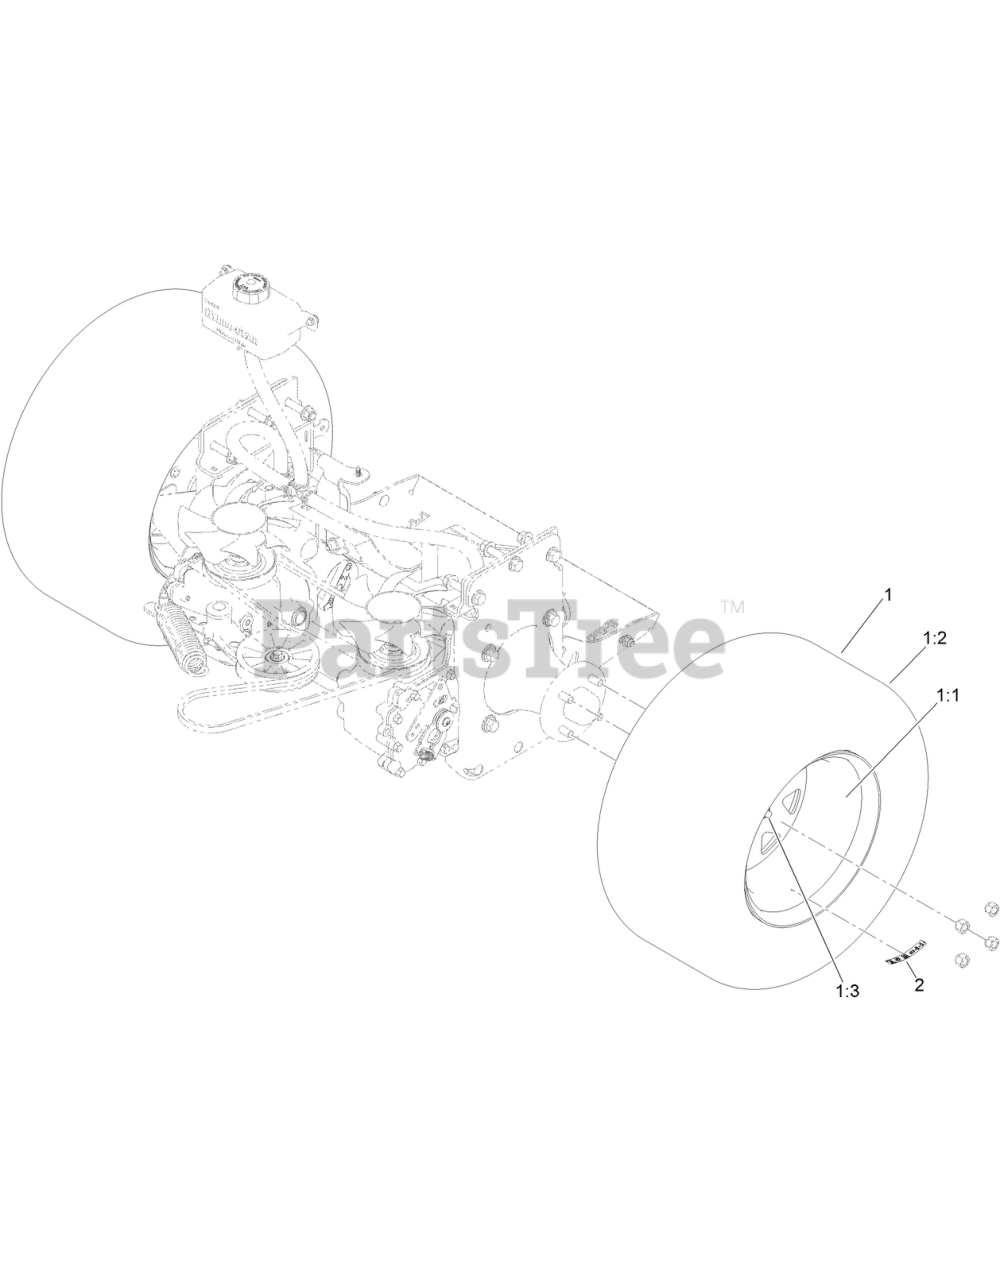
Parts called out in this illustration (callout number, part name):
1	WHEEL AND TIRE ASM
1:1	RIM ASM
1:3	Stem-Valve
2	DECAL-TORQUE, WHEEL HUB LUG
